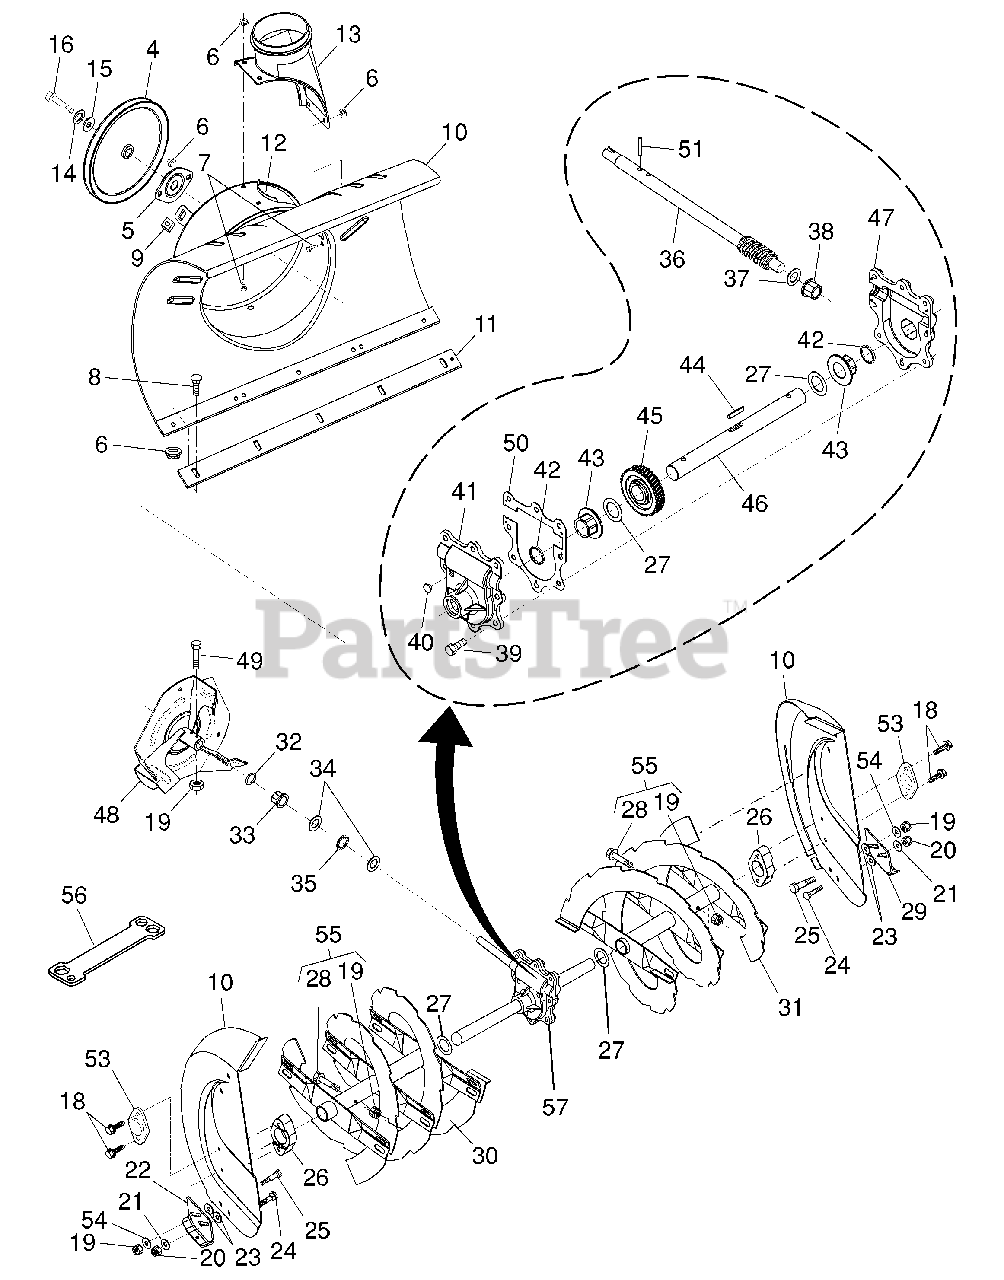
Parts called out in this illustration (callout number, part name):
4	Pulley, Impeller
5	Bearing Assembly, Flange
6	Nut, Hex Flange 5/16-18
7	Bolt, Flat Head, Carriage 5/16-18 x 5/8
8	Bolt, Carriage 5/16-1 8 x 5/8
9	Nut, Cage 3/8-16
10	Housing, Auger
11	Bar, Scraper
12	Bracket, Corner Discharge
13	Base, Discharge Chute
14	Washer, Flat
15	Washer, Lock 5/16
16	Screw, Hex Head 5/16-18 x 3/4
18	Screw, Hex Head 5/16 x 1
19	Nut, Hex Lock 1/4-20
20	Nut, Hex Lock 5/16-18
21	Washer, Flat 5/16
22	Skid Plate, RH
23	Washer, Nylon, Friction
24	Bolt, Carriage 5/16-18 x 3/4
25	Bolt, Shoulder 1/4-20
26	Bearing Retainer, Plastic
27	Washer, Thrust, 1"
28	Bolt, Shear
29	Skid Plate, LH
30	Auger Assembly, RH
31	Auger Assembly, LH
33	Bushing, Flange 3/4
34	Washer, Thrust 3/4
35	Bearing, Thrust 3/4
36	Shaft, Impeller
37	Washer, Thrust 5/8
38	Bushing, Flange 5/8
39	Screw, Hex Head 5/16-18 x 3/4
40	Plug, Case
41	Housing, Gearbox, RH
43	Bushing, Flange, 1"
44	Key, Square 1/4 x 1/4 x 7/8
45	Gear, Worm
46	Shaft, Auger
47	Housing, Gearbox, LH
48	Impeller Assembly
49	Screw, Hex Head 1/4-20 x 1-5/8
50	Gasket, Gearbox
51	Pin, Roll 3/16 x 1-1/8
53	Bearing, Auger
54	Washer, Flat 1/4
55	Kit, Shear
56	Multi-Wrench
57	Gearbox Assembly
